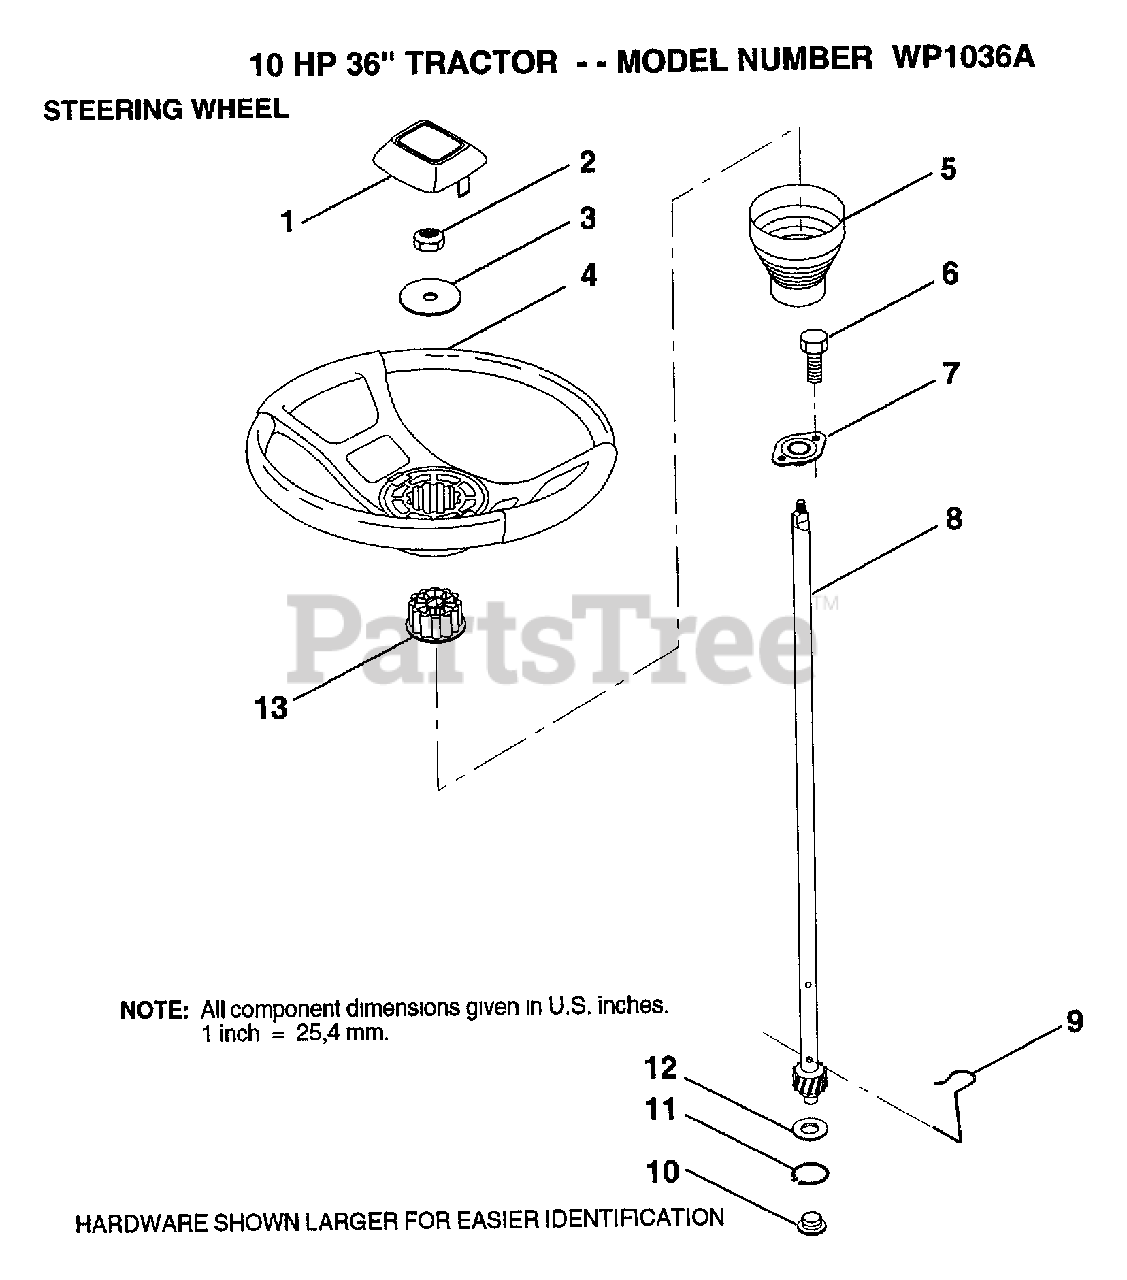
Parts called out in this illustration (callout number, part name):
1	ST WHL INSERT CAP
2	GRIPCO NUT
3	WASHER T
5	SLEEVE STEERING
9	STEERING CLIP
10	BUSHING STEER LWR
11	RING
12	WASHER LT
13	ADAPTER-WHEEL LT
